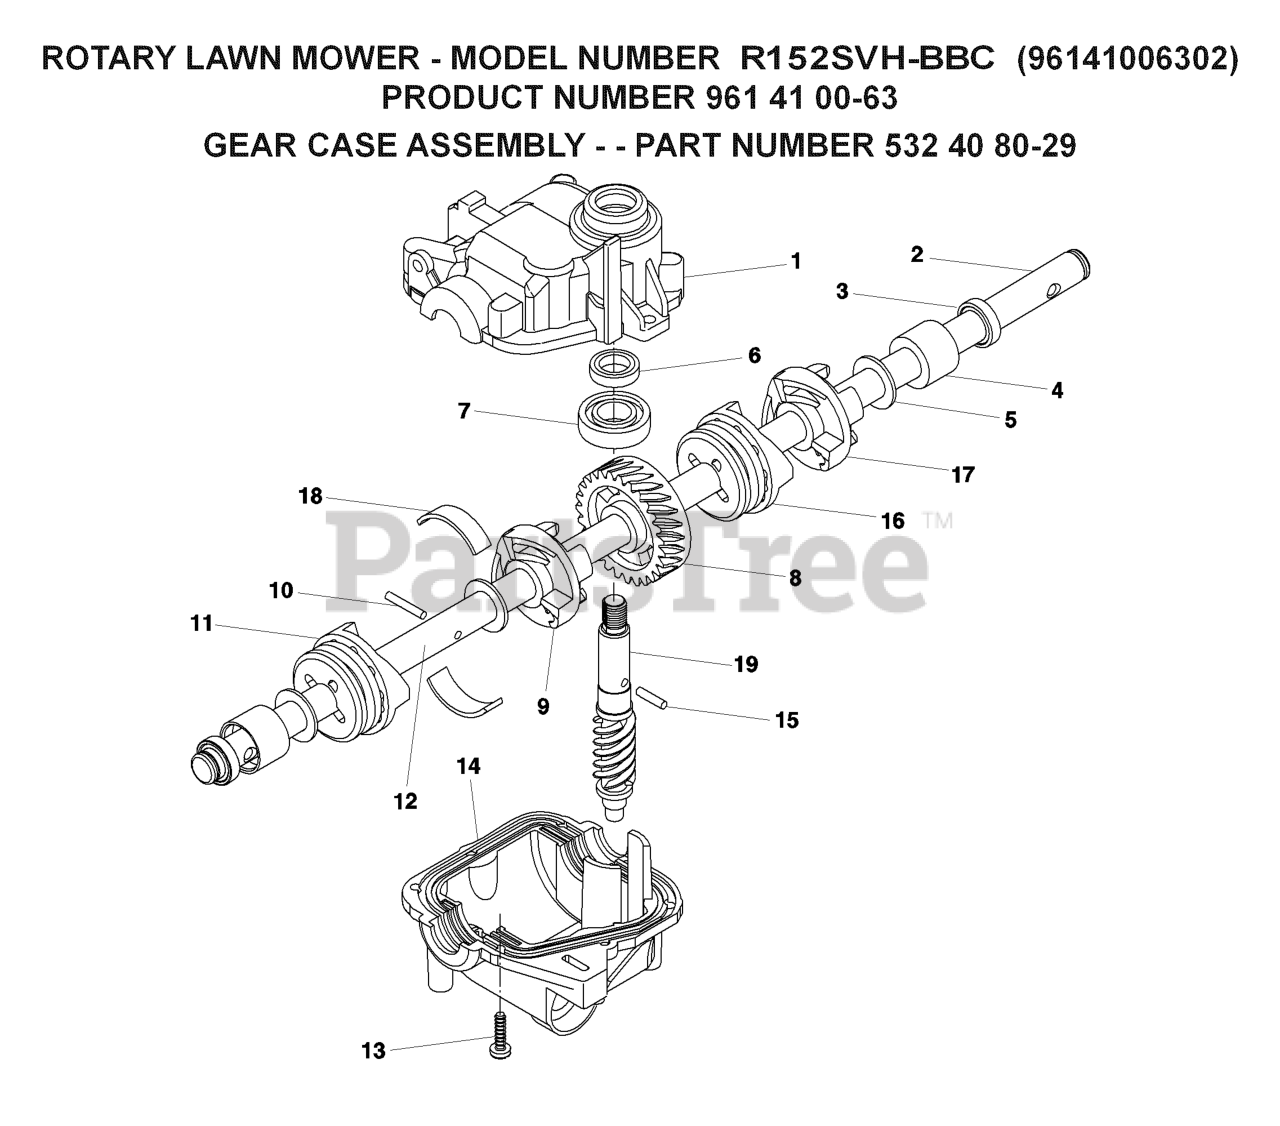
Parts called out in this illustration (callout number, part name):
1	CASE UPPER
3	SEAL.OUTPUT.SHAFT
6	SEAL INPUT SHAFT
8	GEAR 28 TEETH
9	DOG.FIXED.LH.32003
10	PIN 3.50.337 - 33733
11	DOG.MOVEABLE.LH.32005
14	CASE, LOWER
15	PIN 7 33732
16	DOG.FIXED.RH.32004
17	DOG.MOVEABLE.RH.32006
18	SPRING LEAF
